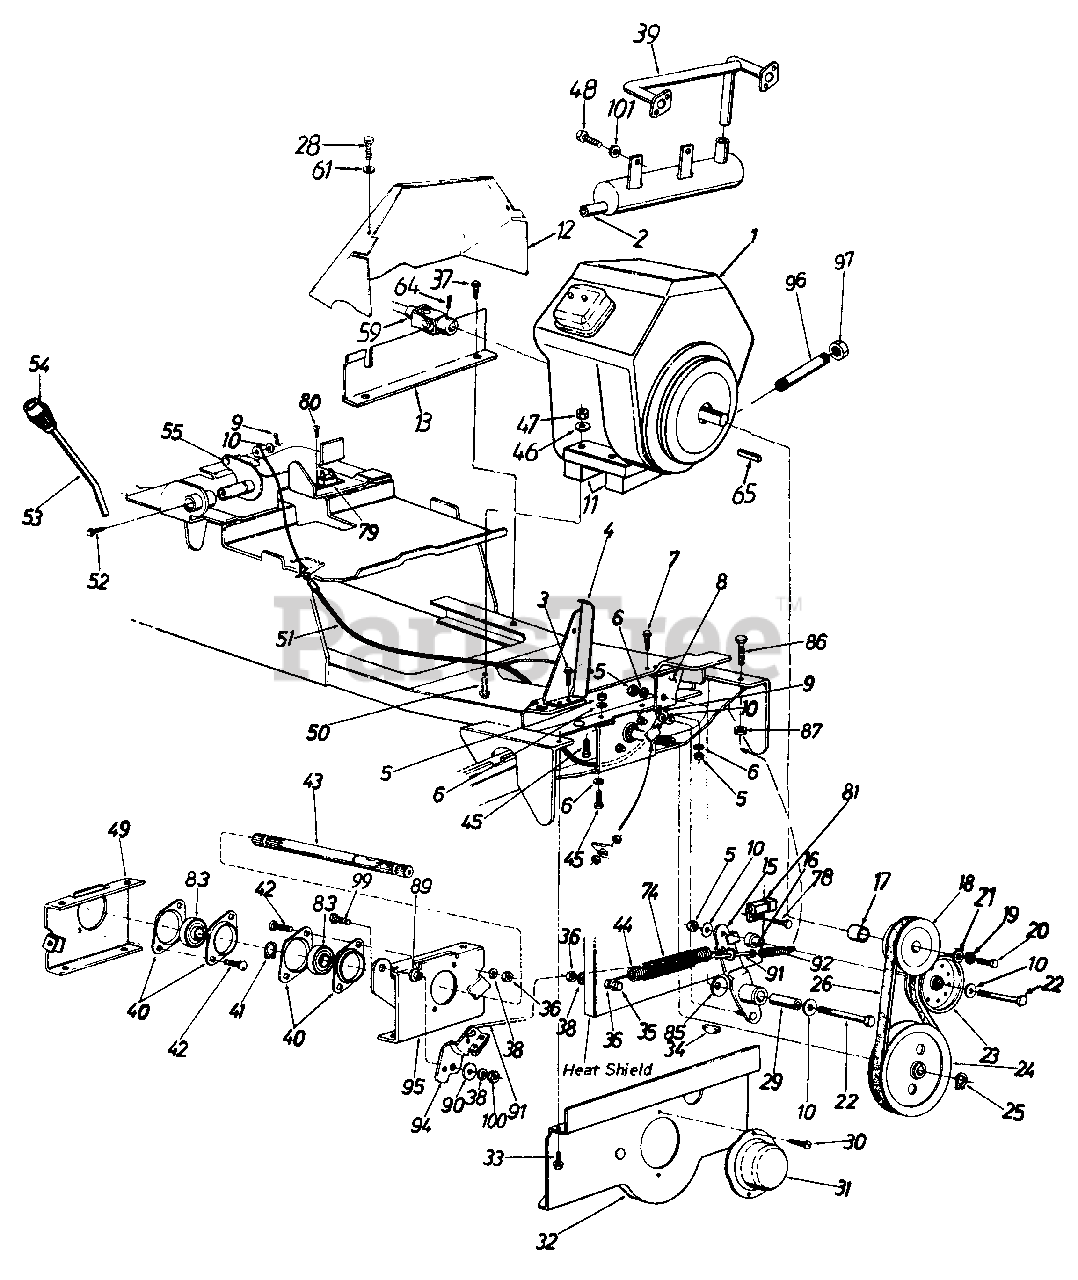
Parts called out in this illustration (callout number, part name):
1	Engine (Kohler)
2	Muffler
3	Hex Wash. Hd. Self-Tap Scr. 1/4-20 x .75" Lg.
6	L-Wash. 3/8" I.D.
7	Hex Wash. Hd. Self-Tap Scr. 5/16-18 x .75" Lg.
10	Fl-Wash .38" I.D. x 1.25" O.D. x .100" Thk.
11	Engine Mounting Spacer
12	Heat Shield
13	Heat Baffle - Lower
17	Pulley Spacer
18	Engine PTO - Pulley
19	L-Wash. 3/8" I.D.
20	Hex Bolt 3/8-16 x 1" Lg.
21	Fl-Wash. 3/8" I.D. x 1.37" O.D.
22	Hex Bolt 3/8-16 x 2.50" Lg.
23	Flat Idler Pulley
25	Snap Ring
26	"V"-Belt (PTO)
28	Hex Bolt M6-1.0 x 10 MM Lg.
29	Spacer .375" I.O. x .62" O.D. x 1.830" Lg.
30	Hex "B" Tap Scr. #10 x .50" Lg.
34	#91 Hi-Pro Key
35	Hex Bolt 5/16-18 x 1.25" Lg.
36	Hex Nut 5/16-18 Thd.
37	Hex Wash. Hd. Tap Scr. 5/16-18 x .5" Lg.
38	L-Wash. 5/16" I.D.
39	Exhaust Pipe
40	1.00" Dia. Brg w/Flangette
41	Snap Ring
42	Carr. Bolt 5/16-18 x .75" Lg.
43	Spline Shaft
44	Extension Spring (PTO Clutch)
45	Hex Bolt 3/8-16 x 1" Lg.
46	L-Wash. 3/8" I.D.
47	Hex Nut 3/8-16 Thd.
48	Hex Bolt 7/16-14 x 1" Lg.
49	PTO Bearing Retainer Brkt.
50	Hex Bolt 3/8-16 x 2.25" Lg
51	PTO Control Cable
52	Hex TT-Tap Scr. 1/4-20 x .5" Lg.
53	PTO Handle
54	Shift Knob
55	PTO Actuator Lever Ass'y.
59	Universal Drive Shaft Comp.
61	Fl-Wash .281" I.D x .5" O.D.
64	Set Scr. 5/16-18 x 38" Lg
65	Sq. Key 1/4" x 2" Lg.
74	Spring Cover Tubing (PTO Clutch)
78	Hex Bolt 1/4-20 x 1/2" Lg.
79	Circuit Breaker
80	Truss Mach Scr. #10 x .50" Lg.
81	Safety Switch (PTO)
83	Ball Bearing
85	Bell-Wash. 39" I.D. x 1.13"
86	Hex Bolt 3/8-16 x 1.5" Lg.
87	Hex L-Nut 3/8-16 Thd.
89	Shoulder Spacer
90	Fl-Wash .33" I.D. x 1.25" O.D
91	PTO Brake Rod
92	Extension Spring 2.15" Lg
94	Brake Ass'y.
95	PTO Brg. Retainer Brkt. Ass'y
96	Pipe Nipple 3/8" x 5" Lg.
97	Oil Drain Cap
99	Hex Bolt 5/16-24 x .75" Lg.
100	Hex Nut 5/16-24 Thd.
101	L-Wash. 7/16" I.D.
